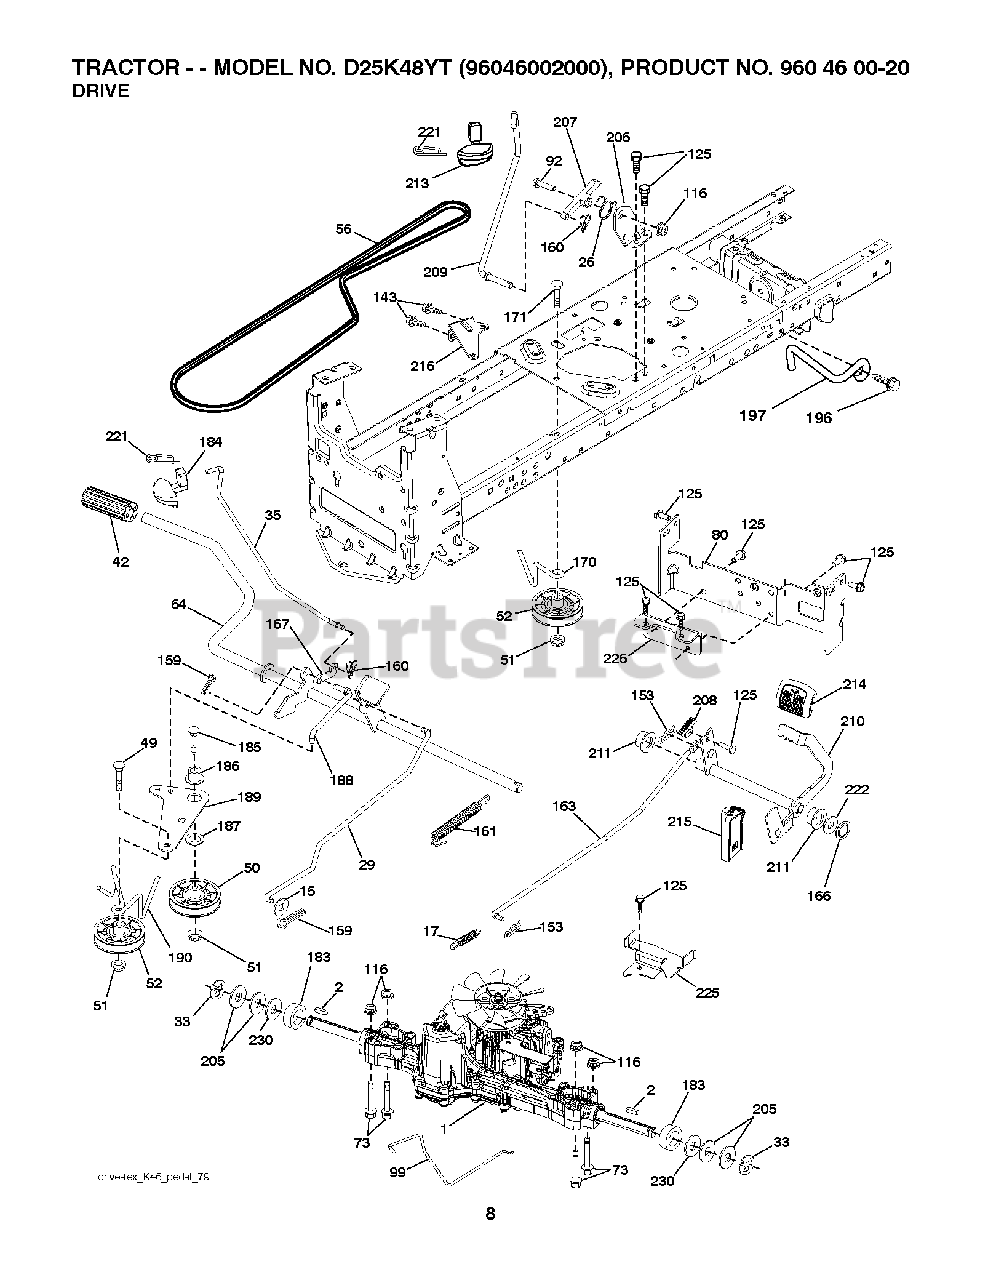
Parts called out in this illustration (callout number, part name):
2	SQUARE KEY
15	WASHER
17	SPRING.BRAKE.K46.GREEN
26	SPRING.RETURN.CRUISE
29	ROD.BRAKE.K46
33	E-RING LT
35	ROD.BRAKE.PARKING.STEALTH
42	PEDAL COVER
50	IDLER.FLAT.910.OFFSET
51	NUT LOCK FLG 3/8-16 UNC
52	IDLER.V-GROOVE.910.OFFSET
56	V-BELT.MOWER.92.40.42/K46
64	SHAFT.ASM.PEDAL.BRK.CNTR
73	BOLT HEX 5/16-18 GR 5
80	STRAP TORQUE
92	BOLT
99	ROD.SPRING.BYPASS.K46.LT.Z
116	NUT LOCK HEX FLANGE 5/16-18
125	SCREW
143	SCREW LT
153	RETAINER M
159	COTTER PIN
160	RETAINER CLIP
161	SPRING, RETURN LT
163	ROD.CONTROL.PEDAL.K46
166	NUT.PUSH.625
167	LATCH.BRAKE.SPRING
170	KEEPER.V-IDLER.CENTER.
183	SPACER AXLE
184	HANDLE.PRKG.BRAKE.STLTH.TX.RED
186	SPACER.RETAINER
187	WASHER 12/32X2X10GA
188	LINK.CLUTCH.GROUND.DRIVE
189	BELLCRANK.GROUND.DRIVE.TEX.
190	KEEPER.BELLCRANK.DRIVE
196	SCREW 3/8-16X1
197	LINK.CLUTCH.ANIT-ROTAT
206	BRKT.MOUNT.LATCH.CRUIS
207	LATCH.CONTROL.CRUISE
208	GEAR.SECTOR.CONTROL.CR
209	ROD.CONTROL.CRUISE.STEALTH.TEX
210	ROCKER.ASM.PEDAL.CONTR
211	BEARING.NYLON
213	KNOB.CONTROL.CRUISE
214	PEDAL.FORWARD.PAD.TEX
215	PEDAL.REVERSE.TEX.GT.4
216	BRACKET.PULLEY.IDLER.W/TEX
221	RETAINER.SPRING.CLIP.H
222	WASHER 21/32 X 1-1/4 X 10 GA.
225	KEEPER.BELT.TRANSAXLE.K46
226	BRACKET.MOUNT.TORQUE.K46.TLT
230	WASHER.HARDENED
